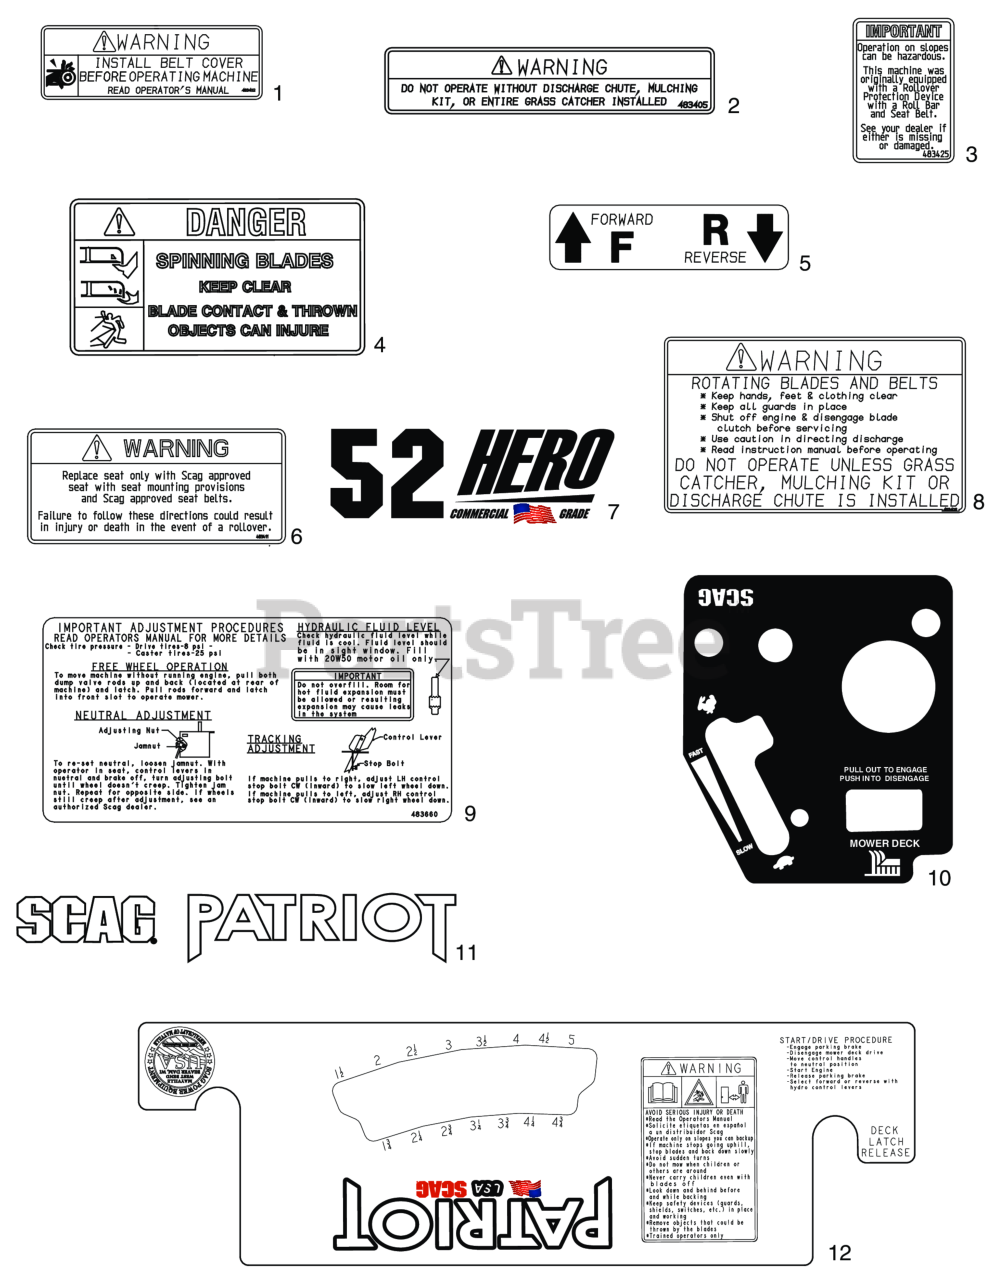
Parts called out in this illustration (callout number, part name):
1	Decal, Warning - Belt Cover
2	Decal, Warning-Discharge
3	Decal, ROPS
4	Decal, Spinning Blades
5	Decal, Traction Control
6	Decal, Seat Replacement
7	Decal, 61 Hero Commercial
8	Decal, Warning - Rotating Blades
9	Decal, Adjustment SFZ
10	Decal, Instrument Panel
11	Decal, Scag RH Fuel Tank
12	Decal, Cutting Height, (Scag Gold Logo)
